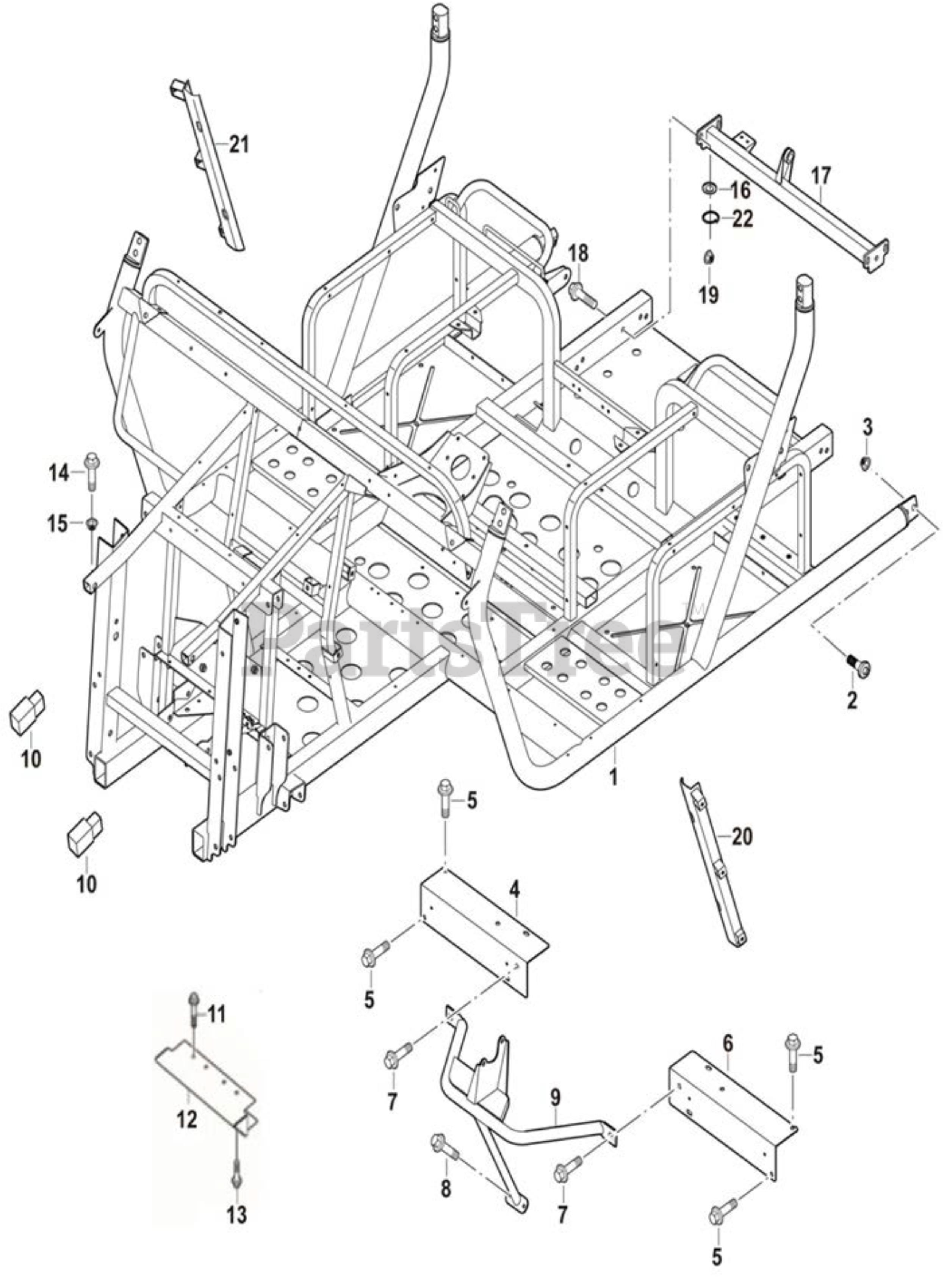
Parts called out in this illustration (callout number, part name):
1	Frame Forepart Assy
2	Hexagon Flange BoltM10X1.25X45
3	Hexagon Flange Self-Lock Nuts M10x1.25
4	Seat Support Plate II
5	Hexagon Flange Bolt M8X16
6	Seat Support Plate I
7	Hexagon Flange bolt M10X1.25X25
8	Hexagon Flange Bolt M6X16
9	Assembling Assy, selector mechanism
10	Left Hinge Plate, Front Panel
11	Hexagon Flange Bolt M12X1.25X35
12	Mounting plate for winch
13	Hexagon Flange Bolt M10X1.25X25
14	Hexagon Flange Bolt M10X1.25X60
15	Hexagon Flange Self-Lock Nuts M10x1.25
16	Flat Washer 10
17	Gearshift Bracket
18	Hexagon Flange BoltM10X1.2560
19	Hexagon Flange Self-Lock Nuts M10x1.25
20	Mounting Bracket, Left Fender
21	Mounting Bracket, Right Fender
22	Spring Washer10
